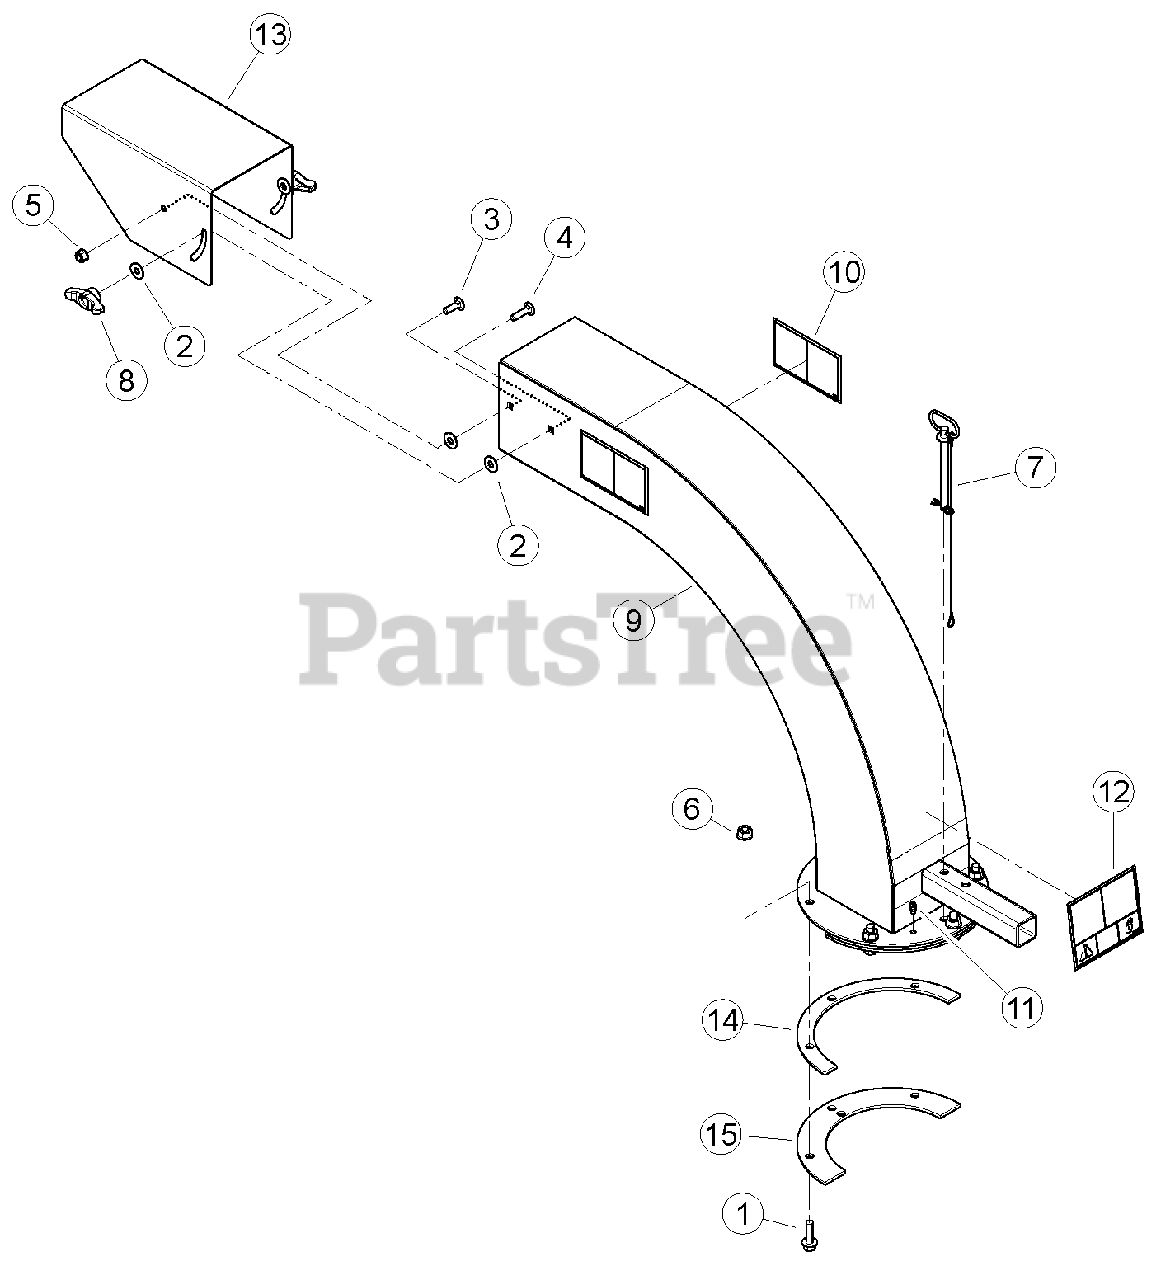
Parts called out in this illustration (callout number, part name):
1	BOLT, 3/8 X 1-1/4 FLANGE NC
2	WASHER, 5/16 FLAT ZP
3	BOLT, 5/16 X 1" GR5 CRG ZP
4	BOLT, 5/16 X 1-1/4 GR5 CRG ZP
5	NUT, 5/16-18 NYLOCK-FLANGE
6	NUT, 3/8-16 NYLOCK FLANGE
7	PIN, 3/8 X 4.25 DISCHARGE
8	KNOB, 5/16-18 UNC TEE W/ LOCKING INSERT
9	ASSEMBLY, 6 INCH ORCHARD DISCHARGE CHUTE
10	DECAL, DISCHARGE ISO
11	FITTING, 1/4 SELF-TAP GREASE
12	DECAL, DISCHARGE DEBRIS & LOCK
13	CAP, 6 INCH ORCHARD DISCHARGE
14	SPACER, DISCHARGE PIVOT
15	RING, DISCHARGE CLAMP
